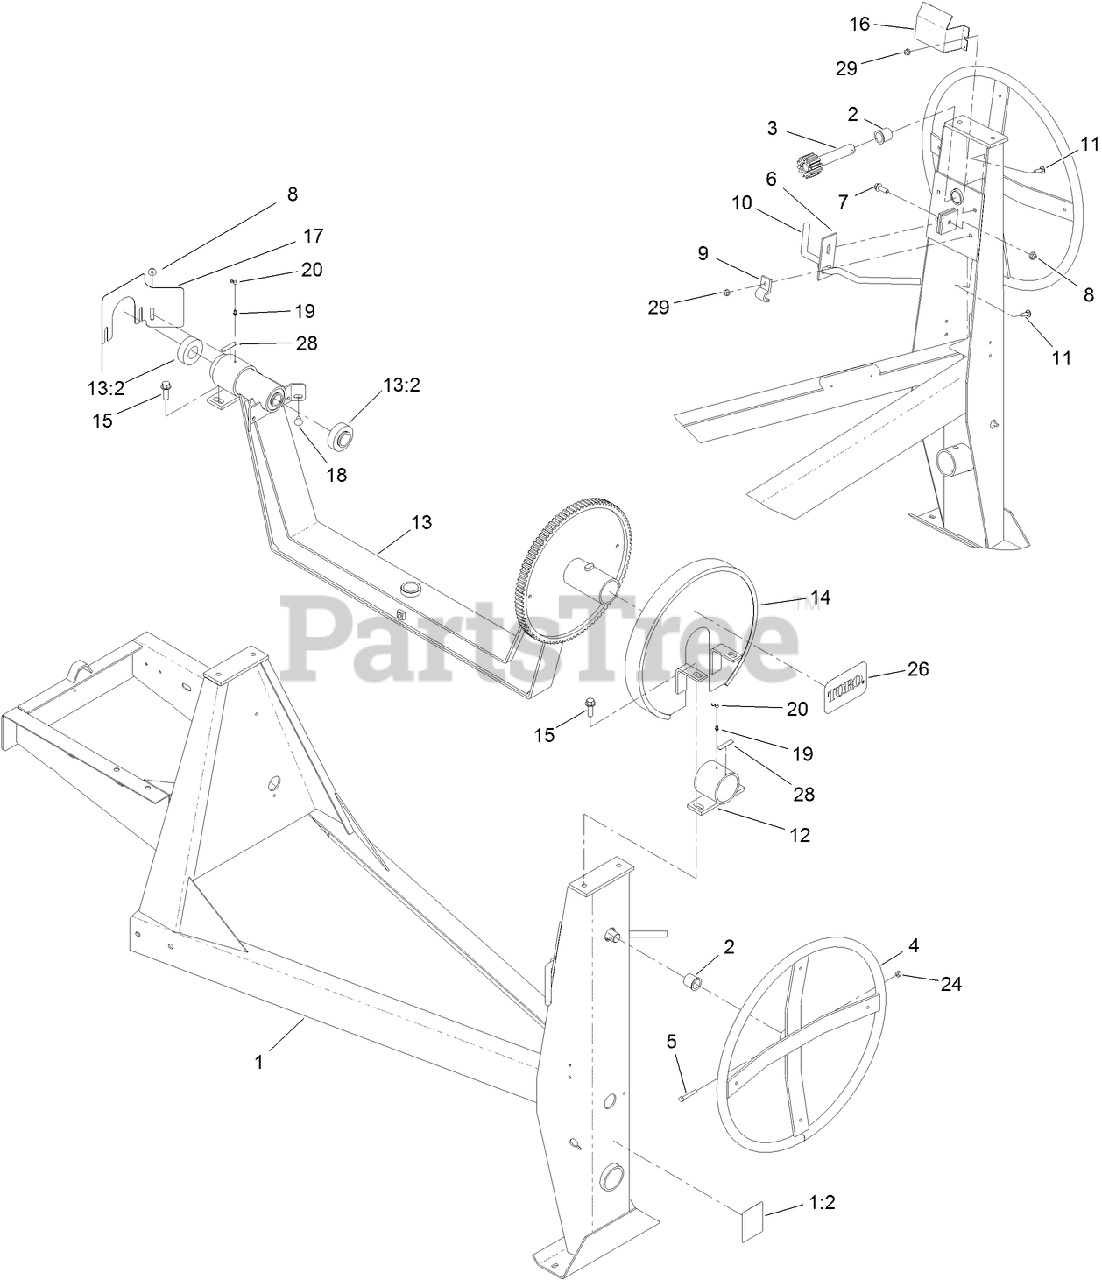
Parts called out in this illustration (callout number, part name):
1	FRAME ASM
1:2	DECAL-SAFETY CHAIN, TOWING
2	BUSHING-NYLON
3	SHAFT-TILT
4	HANDWHEEL
5	SCREW-HH
6	DOG-BRAKE
7	SCREW-HHF
8	NUT-HF, NI
9	BRACKET-HANDLE
10	HANDLE-BRAKE
11	BOLT-CARR
12	TRUNNION
13	YOKE ASM
13:2	BEARING
14	GUARD-BRAKE, UPPER
15	SCREW-HWH
16	GUARD-BRAKE, LOWER
17	GUARD-PINION
18	SCREW-CARR
19	FITTING-GREASE
20	CAP-PLUG
24	NUT-LOCK, NI
26	DECAL
28	DECAL-GREASE
29	NUT-HF, NI
